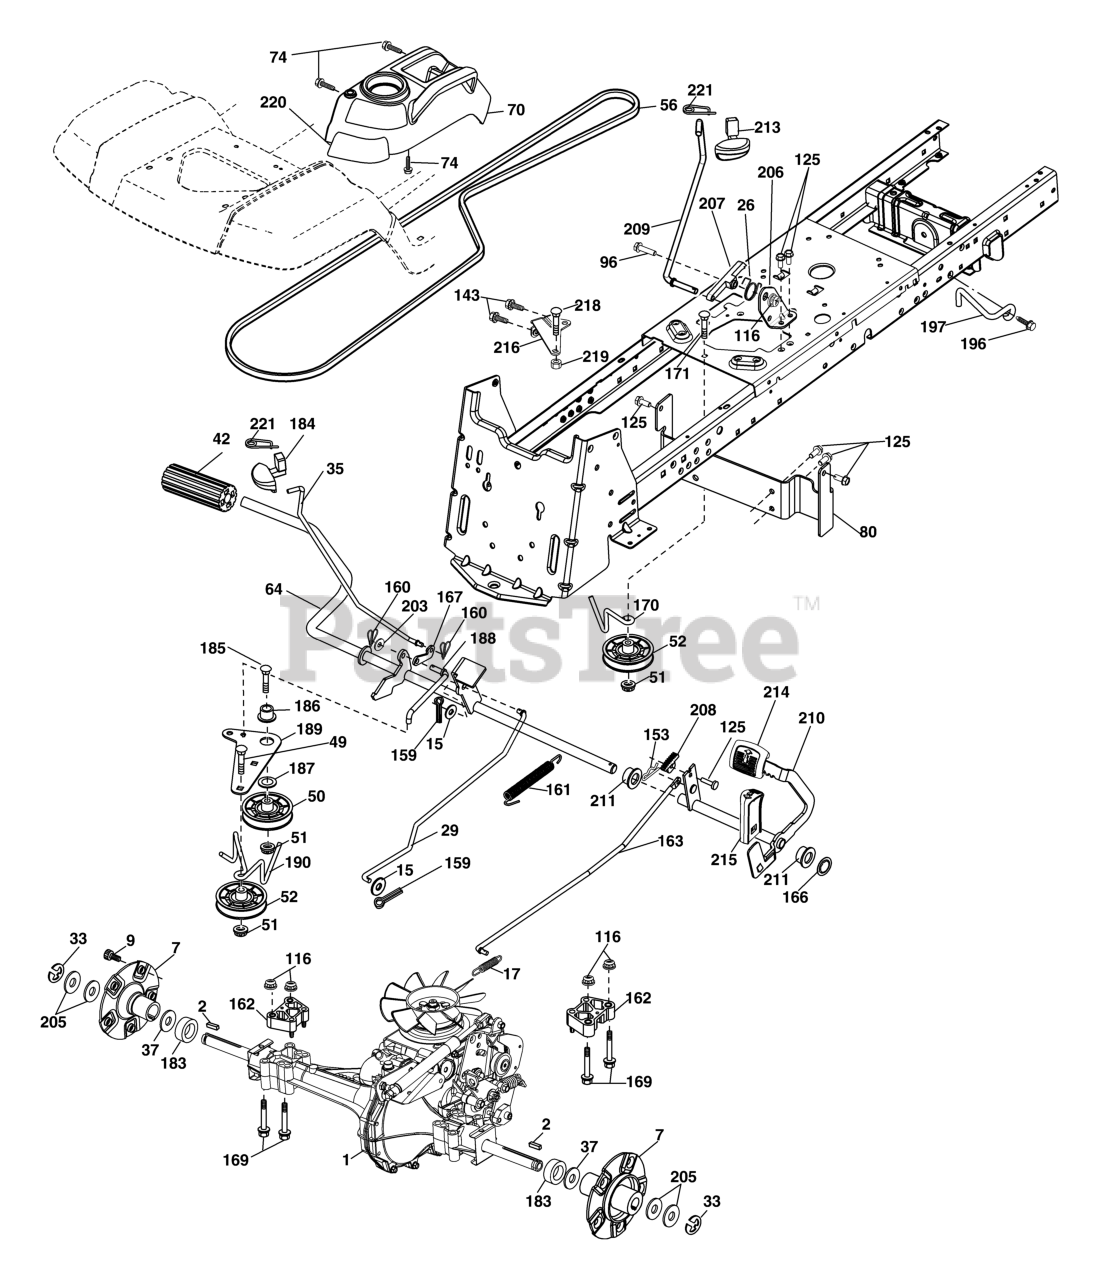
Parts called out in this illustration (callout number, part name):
2	KEY.SQUARE.187X2.500
7	HUB.ASM.WHEEL.REAR.22"
9	HUB BOLT
15	WASHER
17	SPRING.BRAKE.HG3000/3500
26	SPRING.RETURN.CRUISE
29	ROD.BRAKE.0610.PEDAL.CONTROL
35	ROD.BRAKE.PARKING.GT.H
42	PEDAL COVER T
49	BOLT
50	IDLER.FLAT.910.OFFSET
51	NUT LOCK FLG 3/8-16 UNC
52	IDLER.V-GROOVE.910.OFFSET
64	SHAFT.ASM.PEDAL.BRK.CNTR
70	RP CONSOLE.ASM.PCH.W/TB
74	SCREW.HI-LO.CONSOLE
80	BRKT.STRP.TRQ.LT.HYD.C
96	BOLT
116	NUT LOCK HEX FLANGE 5/16-18
125	SCREW
148	SCREW, 3/8-16X3/4
153	RETAINER M
159	COTTER PIN
160	RETAINER CLIP
161	SPRING.RETURN.CLUTCH.2006
162	SPACER.TRANSAXLE.18&22
163	ROD.PEDAL.CONTROL.0510
166	NUT.PUSH.625.2006
167	LATCH.BRAKE.SPRING
169	BOLT.HEX.FLNG.5/16-18X3.75
170	KEEPER.V-IDLER.CENTER.
171	BOLT
183	SPACER.SPLIT.800X.350
184	HANDLE.PARKG.BRK.HUSQ X667
185	BOLT
186	SPACER.RETAINER
187	WASHER 12/32X2X10GA
188	RP.LINK.CLUTCH.GROUND.DRIVE
189	BELLCRANK.GROUND.DRIVE.TEX.
190	KEEPER.BELLCRANK.DRIVE
196	SCREW 3/8-16X1
197	BRKT.ANIT-ROTATION.CLUTCH
203	WASHER
206	BRKT.MOUNT.LATCH.CRUIS
207	LATCH.CONTROL.CRUISE
208	GEAR.SECTOR.CONTROL.CR
209	ROD.CONTROL.CRUISE.GT.
210	ROCKER.ASM.PEDAL.CONTR
211	BEARING.NYLON
213	KNOB.CONTROL.CRUSIE.HU
214	PEDAL.FORWARD.TEX.GT.4
215	PEDAL.REVERSE.TEX.GT.4
216	BRACKET.PULLEY.IDLER.W/TEX
218	BOLT.5/16-18X1-1/4 FULL.THREAD
219	SPACER.FENDER
220	REFLECTOR.RH.TEX GT
221	RETAINER.SPRING.CLIP.H
